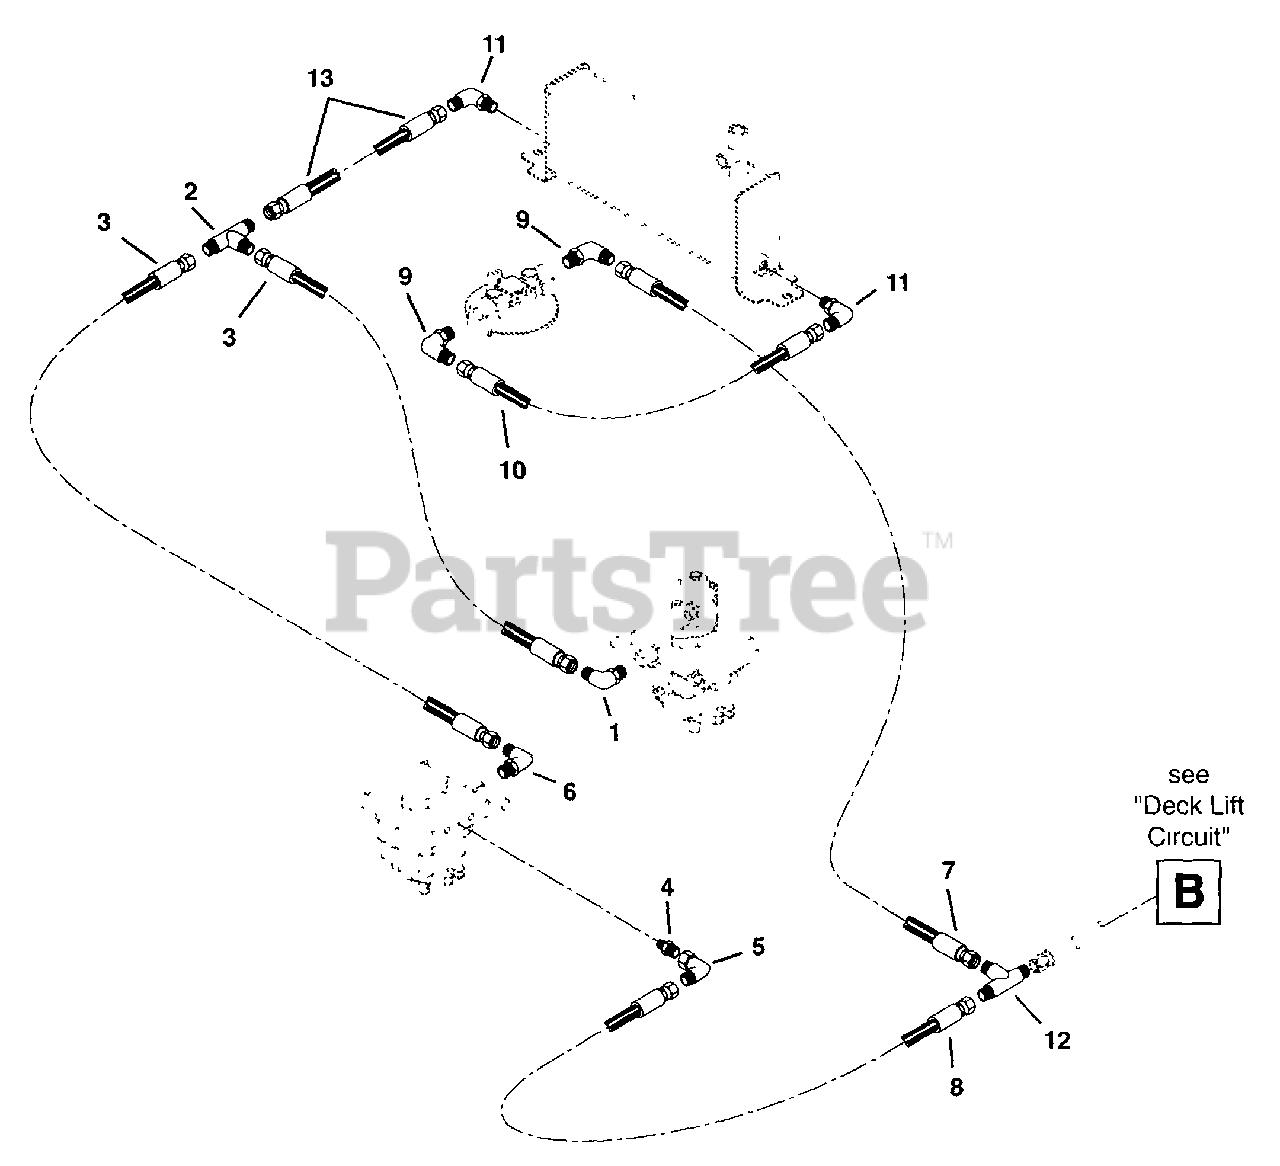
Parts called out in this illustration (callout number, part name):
1	Adapter
2	Adapter-Tee .56-18
3	Hose-Hydraulic Valve to Tank
5	Adapter
6	Adapter
7	Hose-Hydraulic Valve to Tank
8	Hose-Pump to Tee
9	Adapter
10	Hose-Hydraulic Valve to Tank
11	Adapter
12	Adapter-Tee .56-18
13	Hose-Pump to Tee
